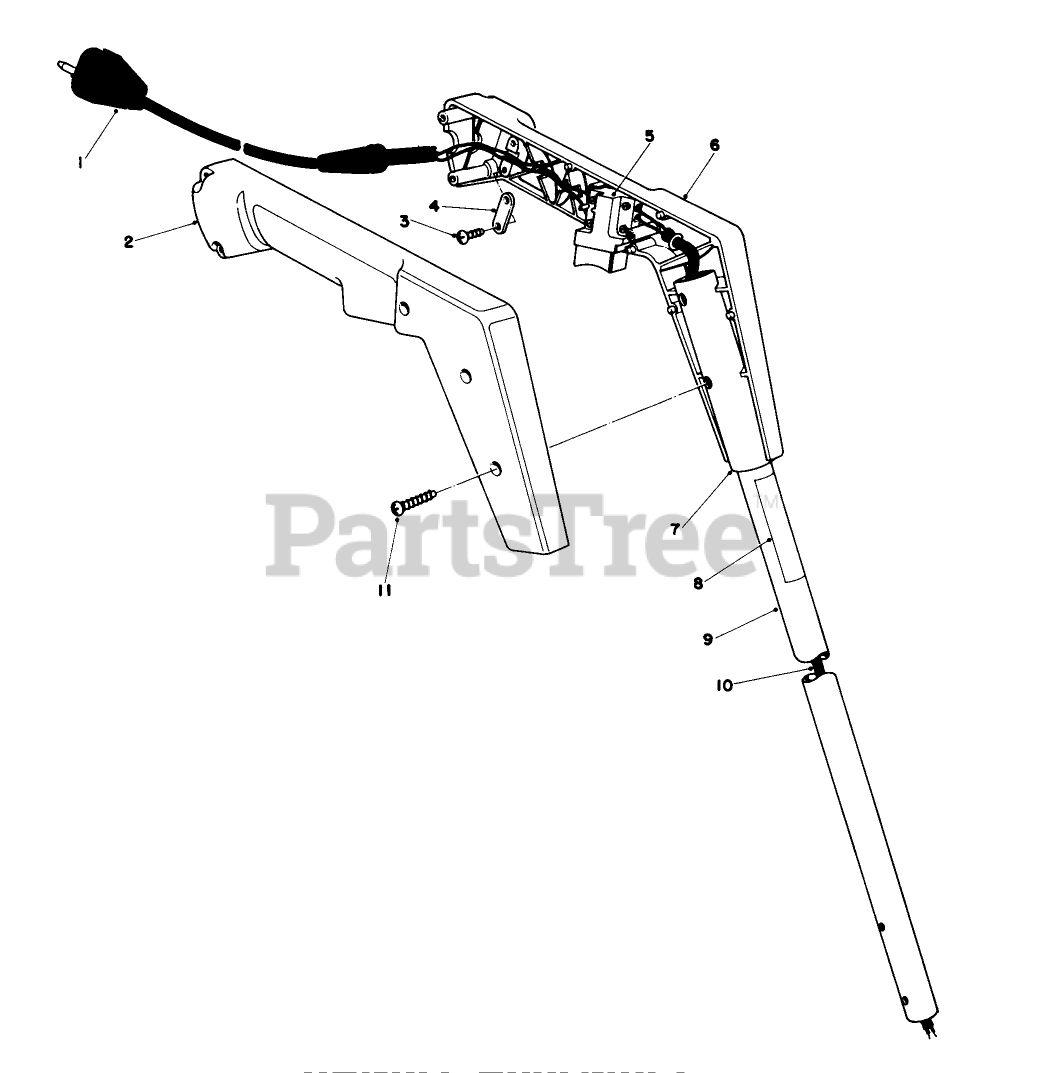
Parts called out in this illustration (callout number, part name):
1	Power Cord
2	Right Hand Grip
3	SCREW-PPH
4	Clamp
5	Switch
6	Left Hand Grip
7	Adapter Sleeve
8	Caution Decal
10	Wire Harness
